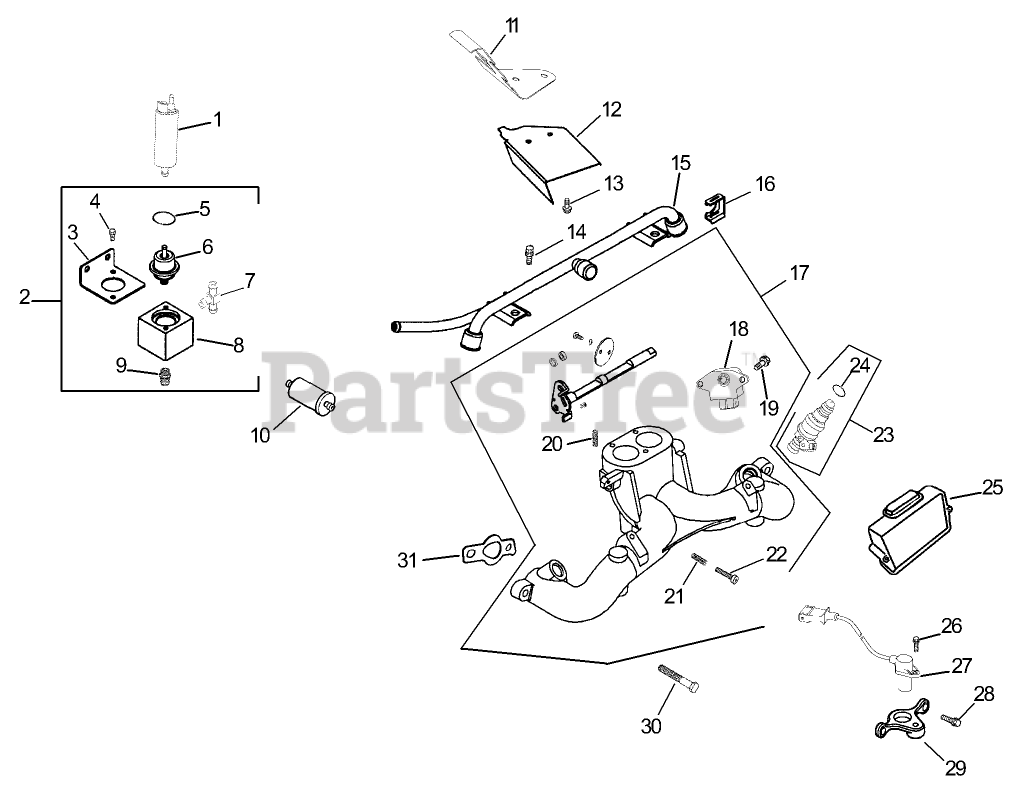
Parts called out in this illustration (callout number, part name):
1	Pump assembly, fuel(Includes 24 050 06-S)
2	Regulator assembly, fuel pressure (Includes 3-9)
3	Bracket-Regulator,Horizontal
4	Screw-HH
5	O-Ring
6	Regulator-Pressure
7	Fitting-Tee
8	Housing-Regulator,Horizontal
9	Connector-Hose, Straight
10	Filter-Fuel
11	Baffle-Valley
12	Deflector-Air
13	SCREW-HHFTF (M5X.80X10)
14	Screw-HF (M6x1.0x10)
15	Rail-Fuel
16	Clip-Injector, Fuel
17	Manifold assembly, intake (Includes 18-22 & 25 454 03-S)
18	Sensor-Position,Throttle
19	Screw-Head, Pan
20	Screw-Set
21	Spring-Control, Speed
22	Screw-HH
23	Injector, fuel (Includes 24)
24	O Ring-Injector, Fuel
25	Control Unit-Electronic (ECU)
26	Screw-HF
27	Sensor-Speed, Engine
28	SCREW-FLANGE, THREAD FORMING (M5X0.8X16)
29	Bracket-Sensor,Speed
30	Screw-HF
31	Gasket-Manifold, Intake
